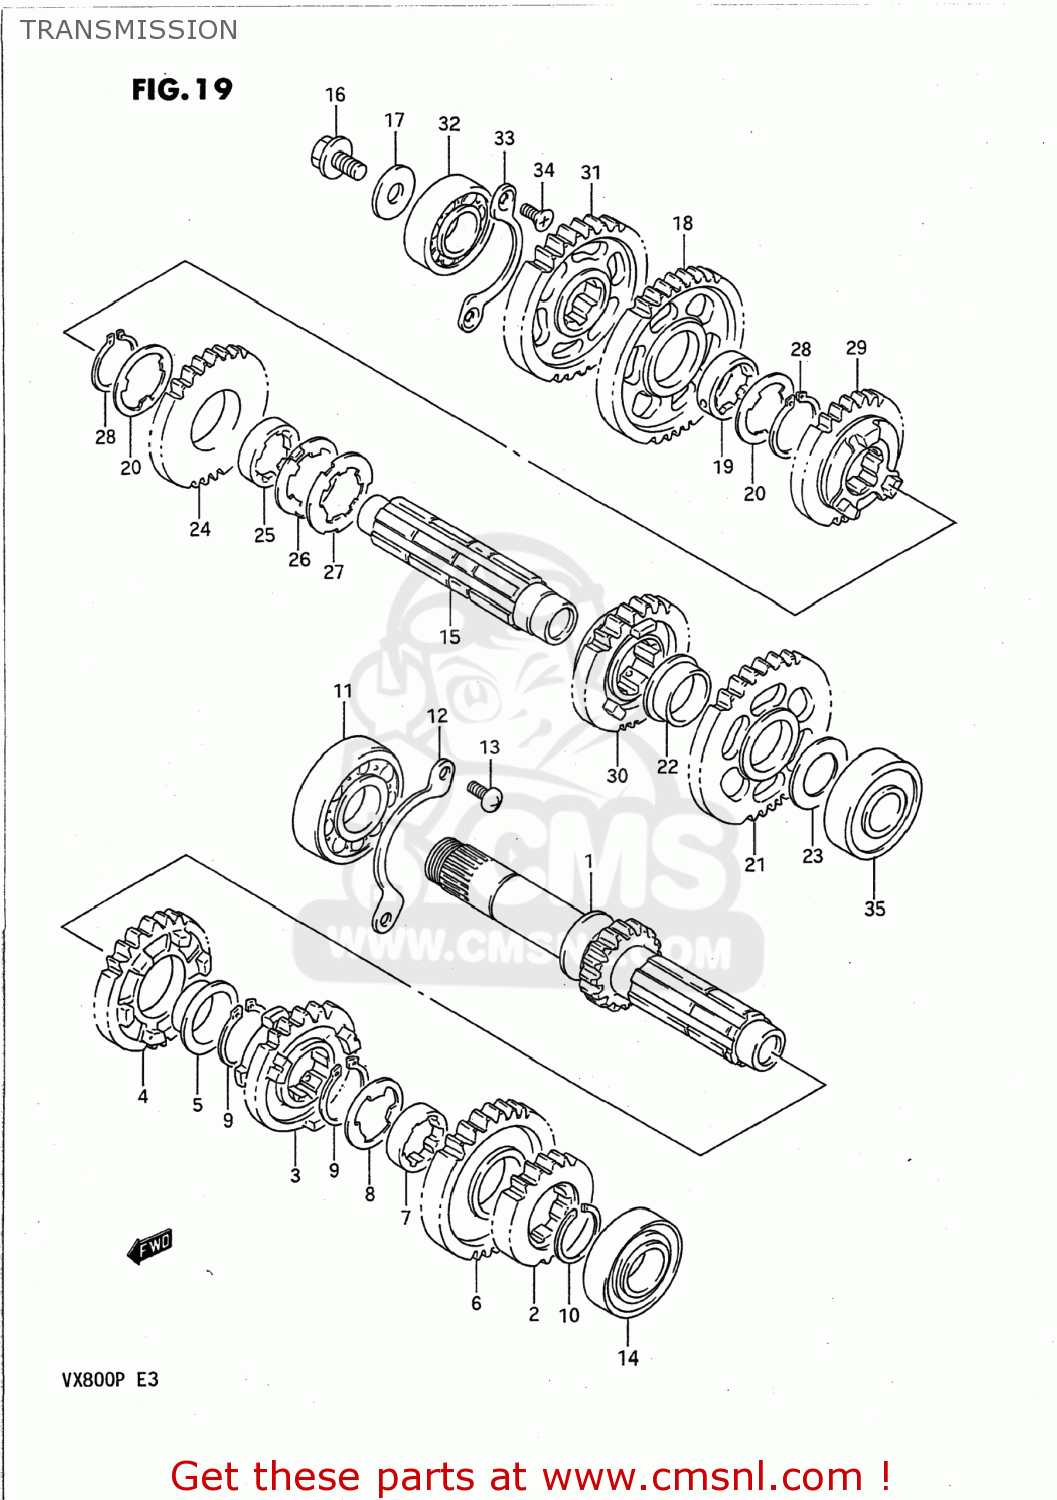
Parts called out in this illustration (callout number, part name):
1	SHAFT,COUNTER
2	GEAR,SECOND DRIVE
3	GEAR,3RD DRIVE(NT:22)
4	GEAR,4TH DRIVE(NT:25)
5	BUSHING
6	GEAR,FIFTH DRIVE (NT:27)
7	BUSHING
8	WASHER,LOCK
9	RING,SNAP
10	CIRCLIP
11	BEARING(25X62X17)
12	RETAINER,CNTR SHAFT BEARING
13	SCREW
14	BEARING 20X47X14
15	SHAFT,DRIVE
16	NOZZLE,DRIVE SHAFT
17	WASHER
18	GEAR,1ST DRIVEN(NT:32)
19	BUSH
20	WASHER,LOCK
21	GEAR,SECOND DRIVEN
22	BUSH
23	WASHER
24	GEAR,3RD DRIVEN(NT:27)
25	BUSH
26	WASHER
27	WASHER,LOCK
28	CIRCLIP
29	GEAR,4TH DRIVEN(NT:25)
30	GEAR,FIFTH DRIVEN (NT:23)
31	GEAR,REDUCTION DRIVE(NT:30)
32	BEARING(20X52X15)
33	RETAINER,DRIVE SHAFT BEARING
34	SCREW
35	BEARING(20X52X15)
